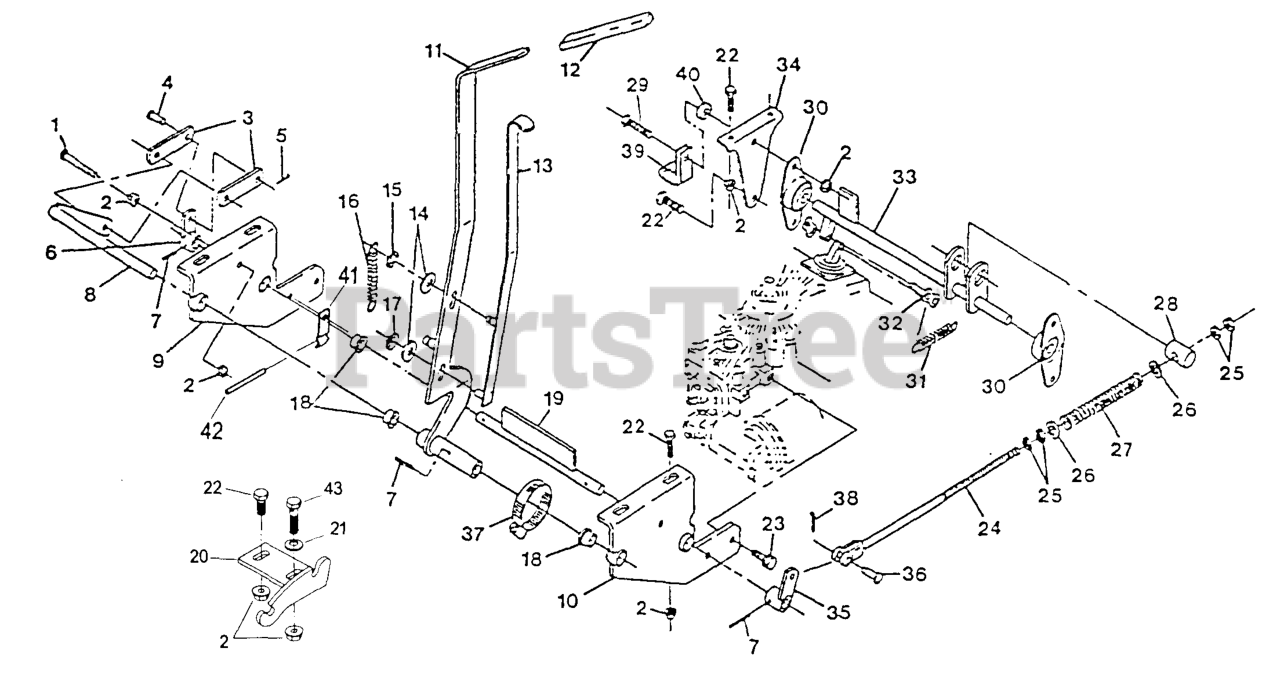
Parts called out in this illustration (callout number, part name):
3	LINK,BRAKE PLTD
4	PIN-CLEVIS
6	WLD,CONTROL ARM
8	PIVOT - BRKT/LEVER
10	WLD,TRANSAXLE SUPPORT RH
12	GRIP-LEVER
16	SPRING,BRAKE HANDLE
17	NUT,PUSH
18	BEARING-CONTROL
19	WLD,BUTTERFLY
20	WLD,BRAKE QUADRANT
21	WASHER-SPRING
24	LINKAGE,BRAKE
27	SPRING,COMPRESSION
28	PIN,TRUNION
30	FLANGE MTG, SIDE
32	LINK,CONNECTING
33	Jackshaft, Brake
35	WLD,BRAKE CONTROL ARM
36	PIN-CLEVIS
37	CLAMP-HOSE
40	SPACER,CLUTCH ANCHOR
41	SPRING,DUMP VALVE
42	ROLLPIN PLTD
